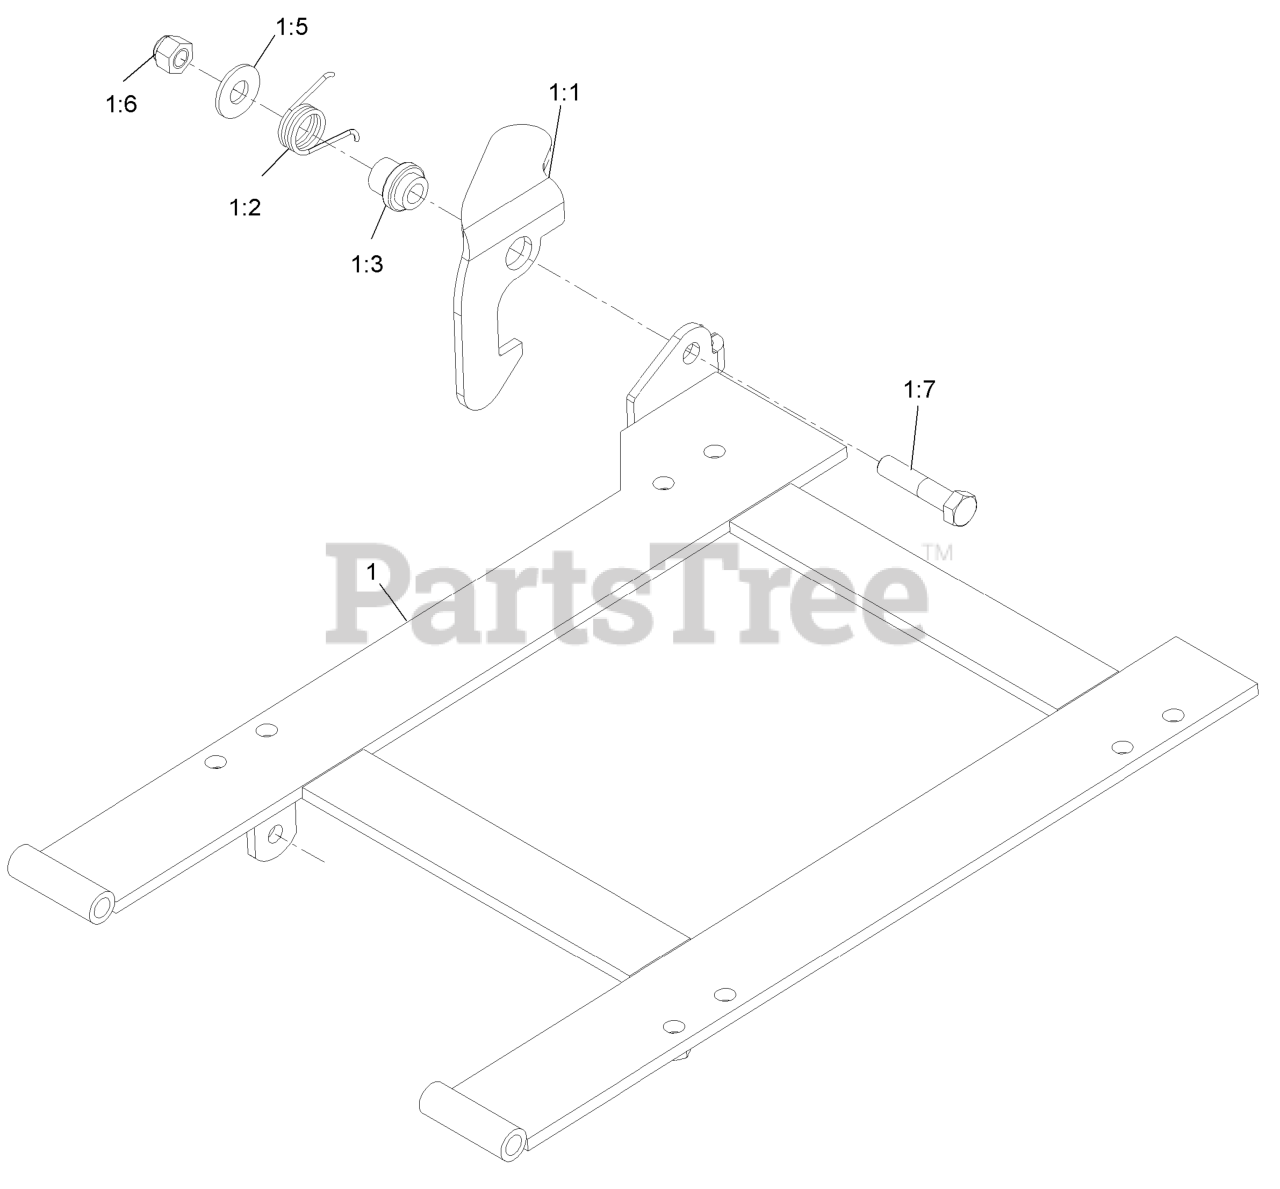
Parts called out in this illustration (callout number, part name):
1	Seat Frame Single Latch ASM
1:1	CATCH-LATCH, SINGLE
1:2	SPRING-TORSION, LATCH
1:3	BUSHING-LATCH, SEAT
1:5	WASHER-FLAT
1:6	NUT-LOCK, NI
1:7	SCREW-HH
